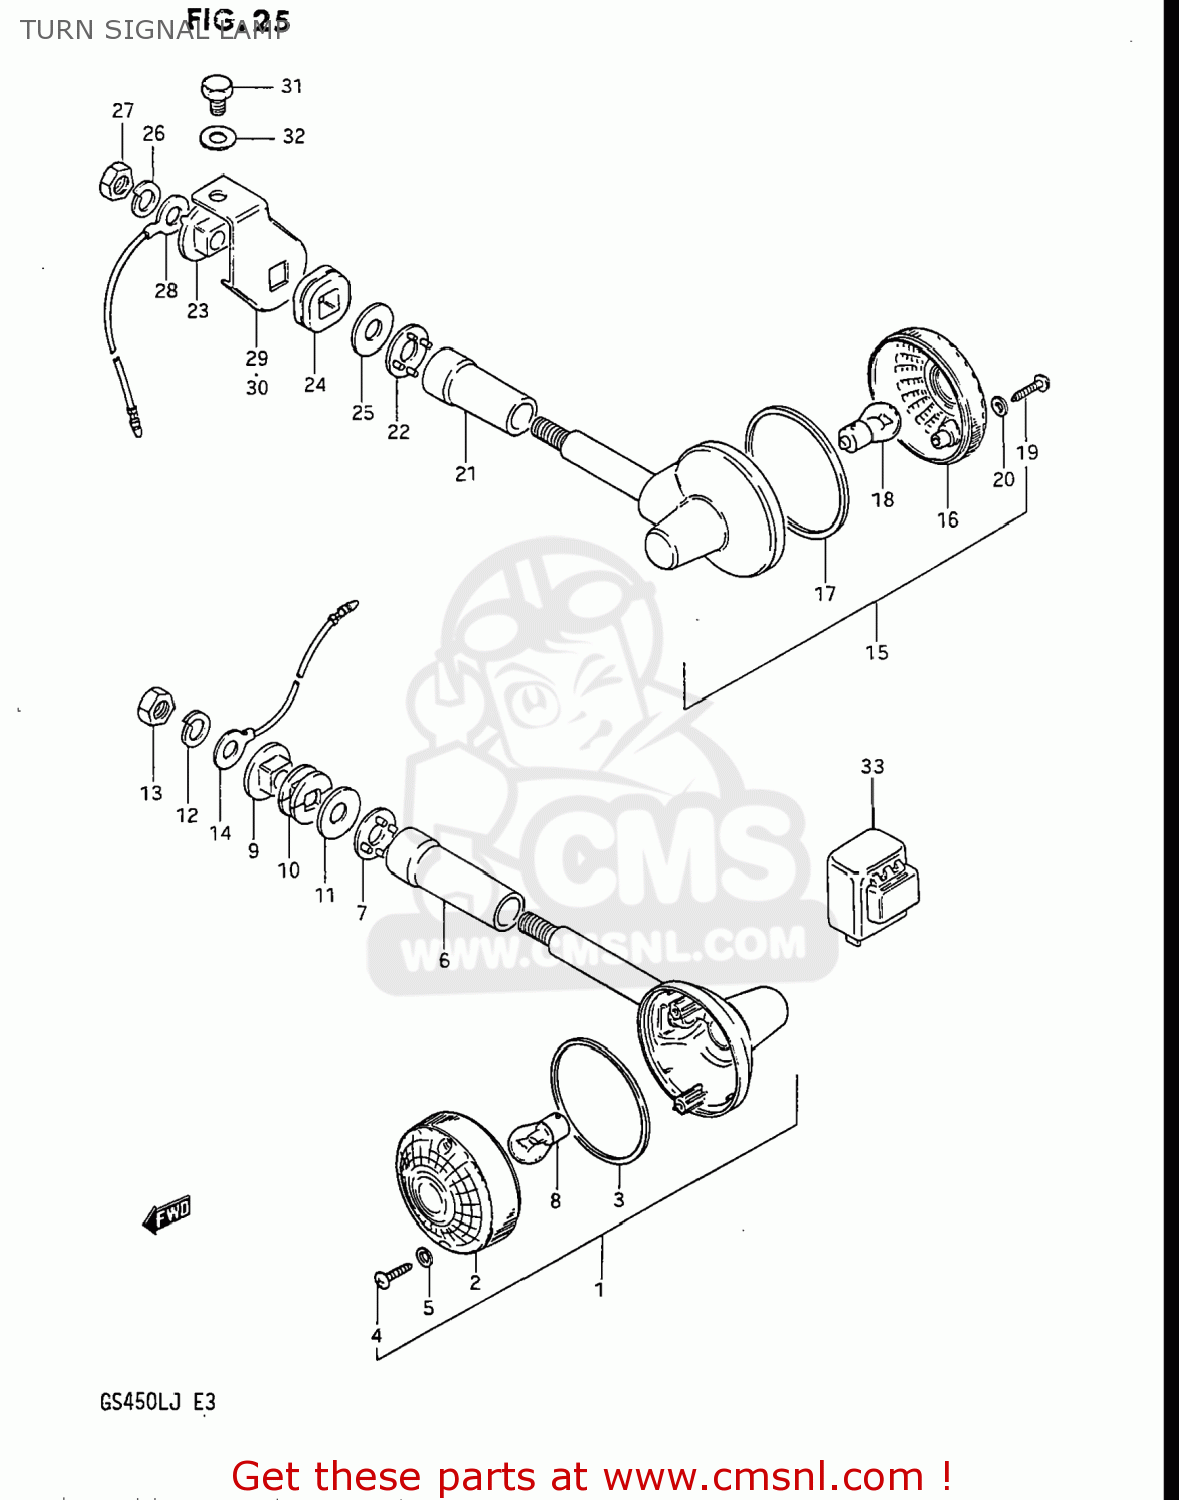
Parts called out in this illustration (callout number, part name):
1	LAMP ASSY,TURNSIGNAL
2	LENS
3	GASKET (NAS)
4	SCREW
5	GASKET (NAS)
6	COVER,STAY
7	SPACER
8	BULB(12V23W,STANLEY,A4577A)
9	SPACER
10	CUSHION
11	WASHER (10.5X30X2.3)
12	LOCK WASHER
13	NUT
14	LEAD WIRE,EARTH
15	LAMP ASSY,RR TURNSIGNAL
16	LENS
17	GASKET (NAS)
18	BULB(12V23W,STANLEY,A4577A)
19	SCREW
20	GASKET (NAS)
21	COVER
22	SPACER
23	SPACER
24	CUSHION
25	WASHER (10.5X30X2.3)
26	LOCK WASHER
27	NUT
28	LEAD WIRE,EARTH
29	BRACKET,RR TURNSIGNAL LAMP,R
30	BRACKET,REAR TURN SIGNAL
31	BOLT
32	WASHER
33	RELAY ASSEMBLY,TURN SIGNAL
